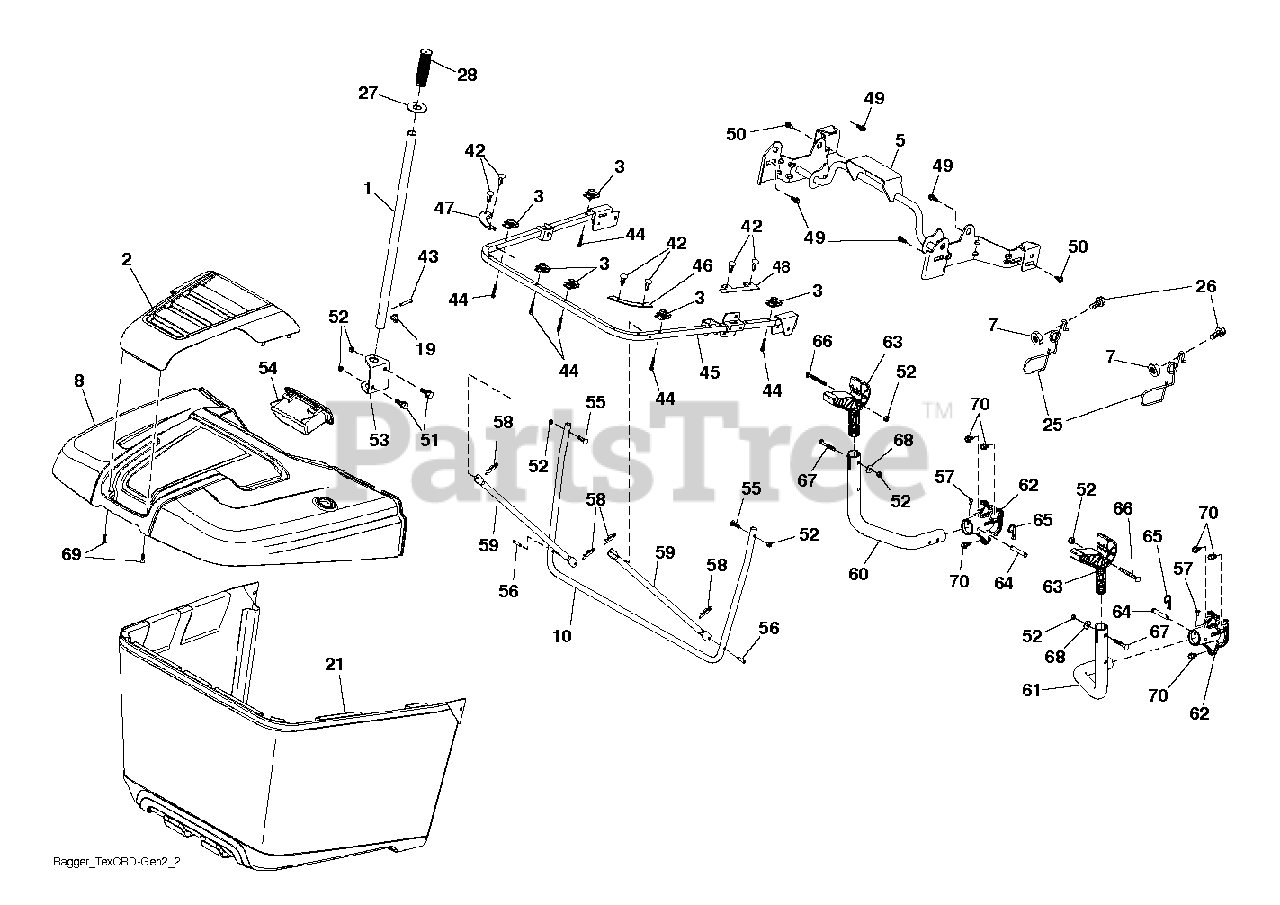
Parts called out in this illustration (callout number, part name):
1	TUBE.HANDLE.BAGGER.CRD/SRD.BLA
2	APPLIQUE.BAGGER
3	1/4-20 U NUT
5	FRAME TEX_CRD_GEN2 UPPER PIVOT
7	NUT T
8	BAGGER TOP
10	FRAME TEX_CRD_GEN2 BAGGER FRAM
19	PIN.COTTER.5/16.BOW TI
21	BAG FRAME BAGGER ASSEMBLY. HUS
25	LATCH LATCH. BAG. CRD GEN 2
26	SCREW HEX CRT
27	GROMMET RUBBER GROMMET, DUMP T
28	GRIP.HANDLE.BLACK
42	CLIP CHRISTMAS TREE CLIP
43	RIVET,DRILLED
45	FRAME TEX_CRD_GEN2 UPPER U FRA
46	CONNECTOR LEFT BAGGER CORNER C
47	CONNECTOR RIGHT BAGGER CORNER
48	BAFFLE BAGGER SIDE CLOSE-OUT
49	BOLT, SHOULDER 5/16-18
50	BOLT, 5/16-18 X 1 3/4
51	BOLT.CARR.SQNK.5/16-18UNC.X3/4
52	NUT.71038.31-18.HEX.NYLOCK
53	BRACKET DUMP HANDLE BRACKET, T
54	HANDLE BAGGER TOP FRONT HANDLE
55	BOLT
56	PIN.CLEVIS.183
57	SCREW T-30 1/4-20 X
58	RETAINER CLIP PM
59	TUBE BAGGER SPREADER TUBE, TEX
65	RETAINER M
69	SCREW,#8.FLAT.HEAD.DRILL.TIP
70	SCREW, 3/8-16X3/4
